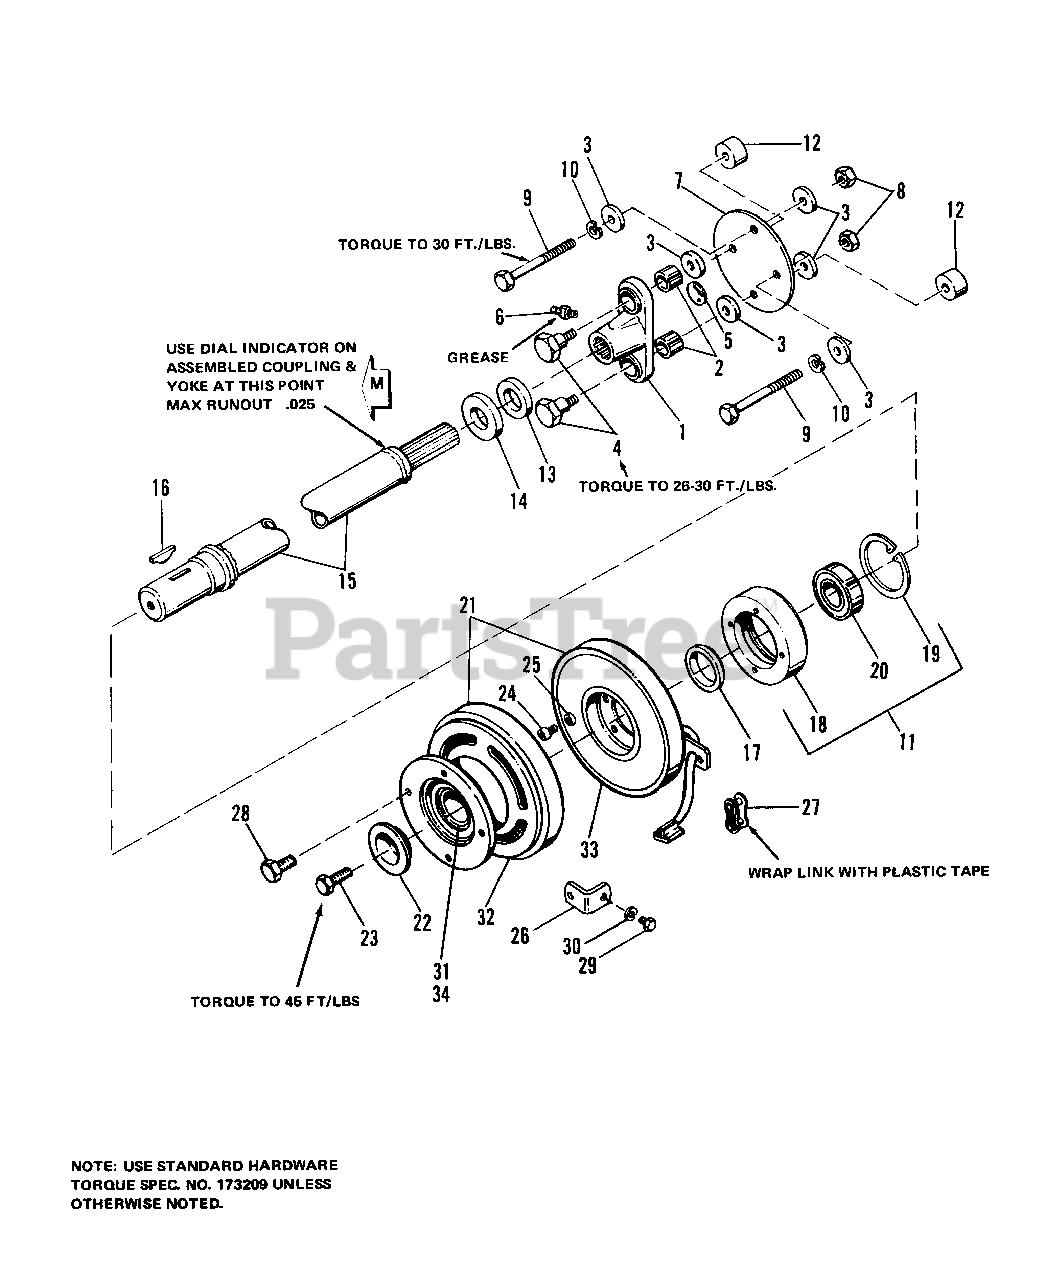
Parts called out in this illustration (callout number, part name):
4	BOLT, Shoulder
6	FITTING, Lube, 1/4-28
8	NUT, Flange, Whiz Lock, 3/8-16
9	CAPSCREW, Hex, 3/8-16 x 3-1/2
10	LOCKWASHER, 3/8
11	BEARING, PTO Retainer
13	WASHER, Felt
14	WASHER, Rubber
15	SHAFT ASSY
18	RETAINER, Bearing
19	RING, Retaining
21	CLUTCH ASSY
23	SCREW, Whiz Lock, 3/8-16 x 1-1/4
24	CAPSCREW, Hex, No. 10-32 x 1/2
25	LOCKWASHER, No. 10
26	BRACKET ASSY
27	LINK, Connect
28	SCREW, Taptite, 5/16-18 x 1
29	CAPSCREW, Hex, 1/4-20 x 3/4
30	LOCKWASHER, 1/4
31	BEARING
32	ROTOR ARMATURE
34	BEARING, Wide Race
